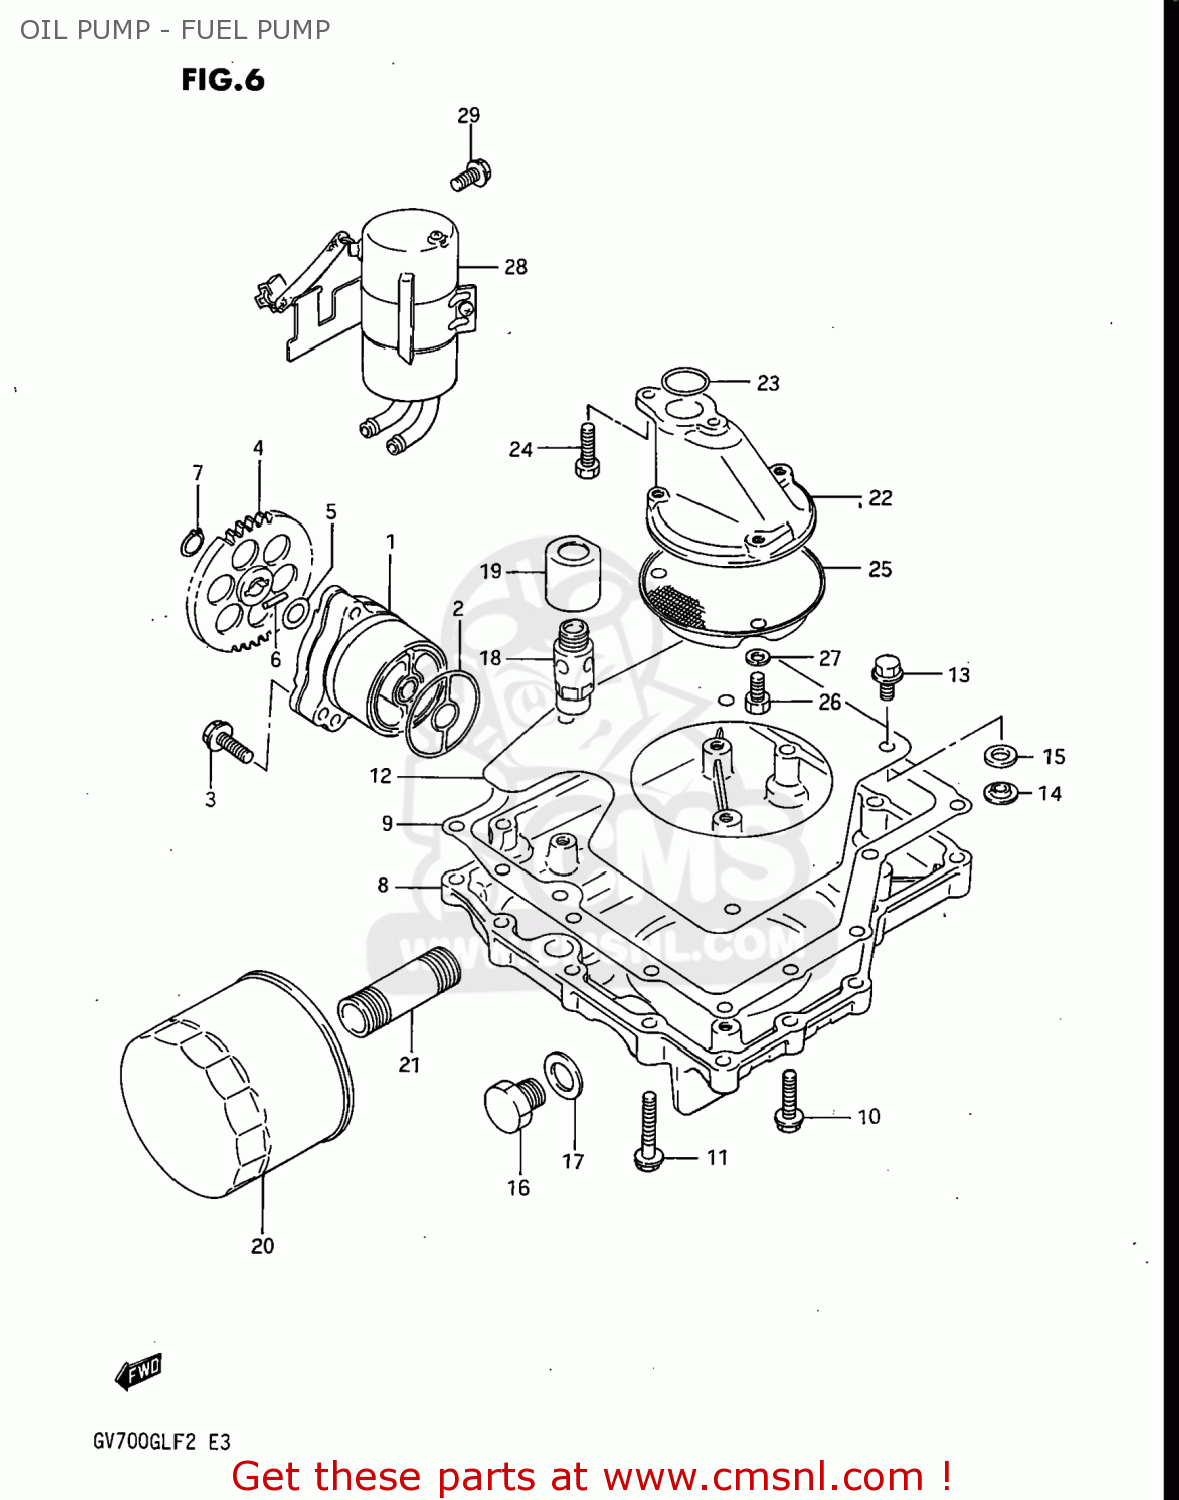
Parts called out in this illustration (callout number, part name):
1	PUMP ASSEMBLY,ENGINE OIL
2	O RING,OIL PUMP
3	BOLT
4	GEAR,OIL PUMP DRIVEN
5	SHIM
6	PIN(4X15.8)
7	CIRCLIP
8	PAN,OIL
9	GASKET,OIL PAN (MCA)
10	BOLT
11	BOLT
13	BOLT
14	WASHER
15	CUSHION
16	PLUG
17	GASKET(14X19.2X2) (NAS)
18	REGULATOR ASSEMBLY,ENGINE
19	GUIDE,OIL RV
20	FILTER ASSY,ENGINE OIL
21	UNION,OIL STAND
22	PROTECTOR,OIL STRAINER
23	O RING(D:3.2,ID:17.8)
24	BOLT,REAR
25	STRAINER,ENGINE OIL
26	BOLT
27	LOCK WASHER
28	PUMP ASSY,FUEL
29	BOLT
